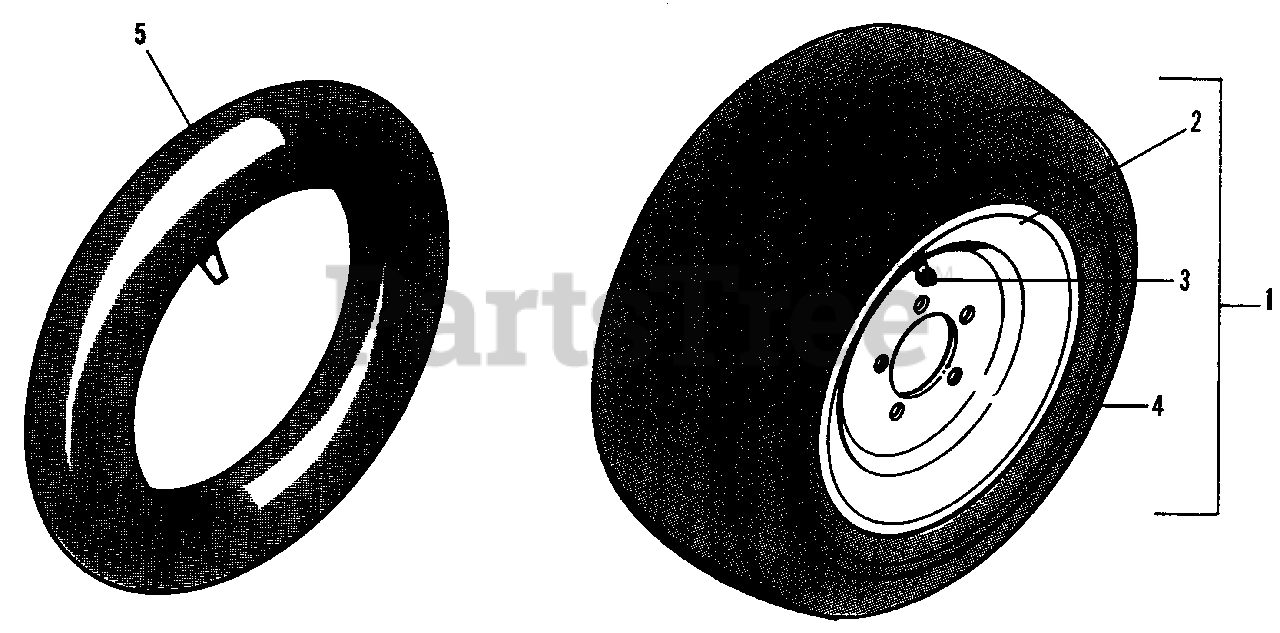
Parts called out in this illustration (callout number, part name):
1	WHEEL & TIRE ASSY., R.H. 26 x 12.00-12
1	WHEEL & TIRE ASSY., LH., 26-12.00-12
3	VALVE STEM & CAP
4	TIRE, Tubeless, Ag., 16-12.00-12
4	TIRE, Tubeless, Turf, 26 x 12.00-12
5	TUBE, 26 x 12 x 12
